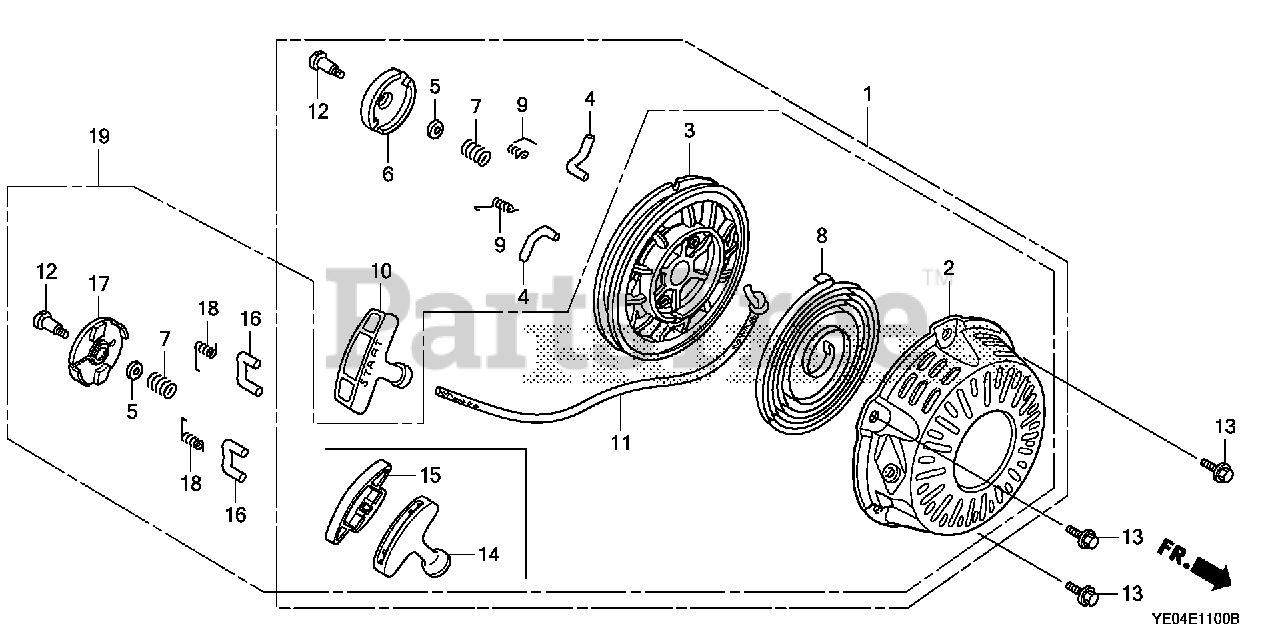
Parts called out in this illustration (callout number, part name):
2	CASE, RECOIL STARTER *R280* (POWER RED)
3	REEL, RECOIL STARTER (BLACK)
5	PLATE, FRICTION
7	SPRING, FRICTION
8	SPRING, RECOIL STARTER
11	ROPE, RECOIL STARTER (#5X55")
12	SCREW, SETTING
13	BOLT, FLANGE (6X8)
14	KNOB, RECOIL STARTER
15	KNOB, REINFORCEMENT
16	RATCHET, STARTER
17	GUIDE, RATCHET
18	SPRING, RETURN
19	STARTER ASSY., RECOIL *R280* (COO)(FOR U.S.A.) (POWER RED)
